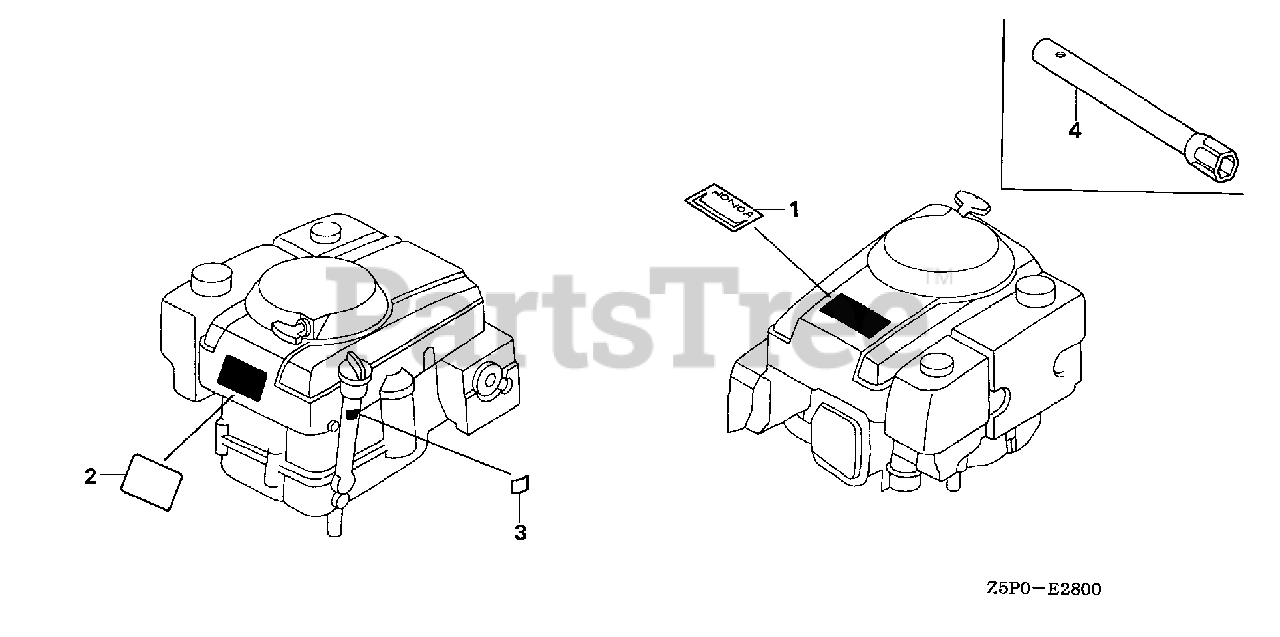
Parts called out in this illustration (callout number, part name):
1	EMBLEM, TOP COVER (11.0)
2	MARK, OPERATOR CAUTION (ENGLISH)(MADE IN THAI)
2	MARK, OPERATOR CAUTION
3	MARK, TYPE (DAS)
4	WRENCH, BOX (P21)
